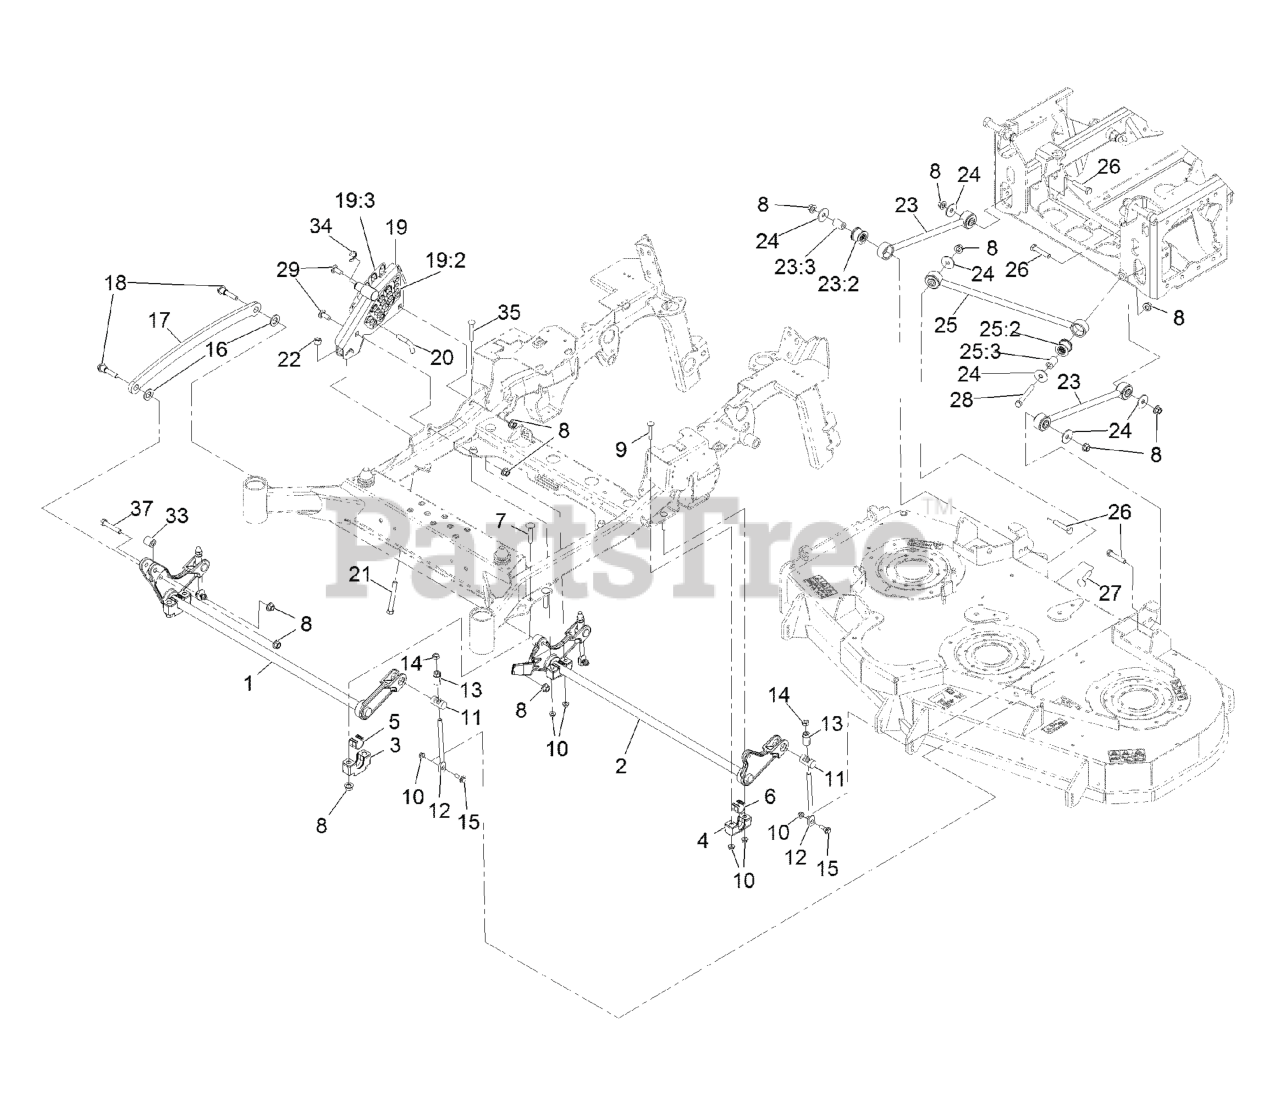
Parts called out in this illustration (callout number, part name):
1	DECKLIFT-FRONT
2	LIFT-DECK, REAR
3	SUPPORT-CROSS SHAFT, BEARING
4	SUPPORT-CROSS SHAFT, BEARING REAR
5	BEARING-CROSS SHAFT, FRON
6	BEARING-CROSS SHAFT, REAR
7	Bolt-Carriage 1/2-13 X 2 1/2 Spl Neck
8	Nut-Lock 1/2-13
9	Bolt-Carriage 3/8-16 X 2 1/4
10	NUT-HF, NI
11	TRUNNION
12	LINK-ADJUSTER, DECK LIFT
13	ADJUSTER-LIFT, DECK
14	NUT-JAM
15	SCREW-SHOULDER, HHF
16	WASHER-FLAT
17	LINK-LIFT, DECK
18	SCREW-HHF, SHOULDER
19	HOC ASM
19:2	DECAL-HEIGHT OF CUT
19:3	DECAL-HEIGHT OF CUT, OUTER
20	PIN-HOC
21	BOLT-TAP
22	NUT-LOCK, NI
23	DECK STRUT ASM
23:2	BUSHING-SUSPENSION, RUBBER
24	WASHER-THRUST
25	PANHARD ROD ASM
25:2	BUSHING-SUSPENSION, RUBBER
26	SCREW-HH
27	SCREW-CARR
28	SCREW-HH
29	SCREW-CARR, SHORT NECK
33	SPACER-PIVOT
34	RING-RETAINING
35	SCREW-CARR
37	SCREW-HH
